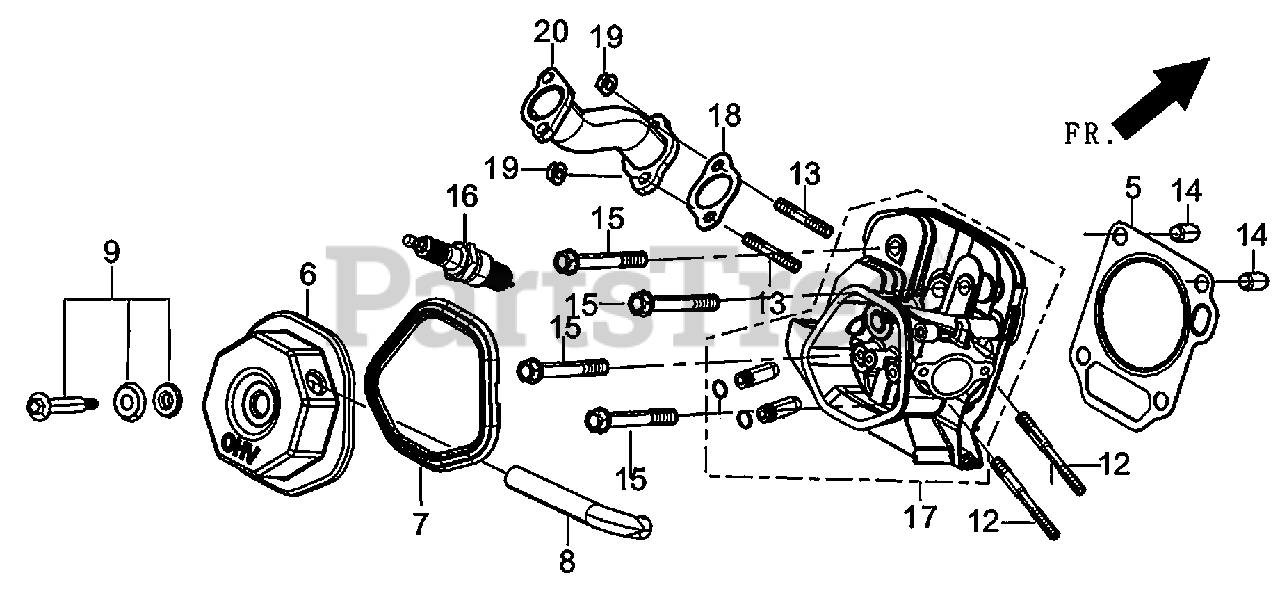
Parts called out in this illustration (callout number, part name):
5	GASKET, CYLINDER HEAD
6	COVER SUBASSEMBLY, CYLINDER HEAD
7	GASKET, CYLINDER HEAD COVER
8	TUBE, BREATHER
9	BOLT SUBASSEMBLY, CYLINDER HEAD COVER
12	STUD, INTAKE
13	STUD, EXHAUST
14	PIN, DOWEL
15	BOLT, CYLINDER HEAD
16	PLUG, SPARK
17	HEAD SUBASSEMBLY, CYLINDER
18	GASKET, EXHAUST OUTLET
20	PIPE, EXHAUST
